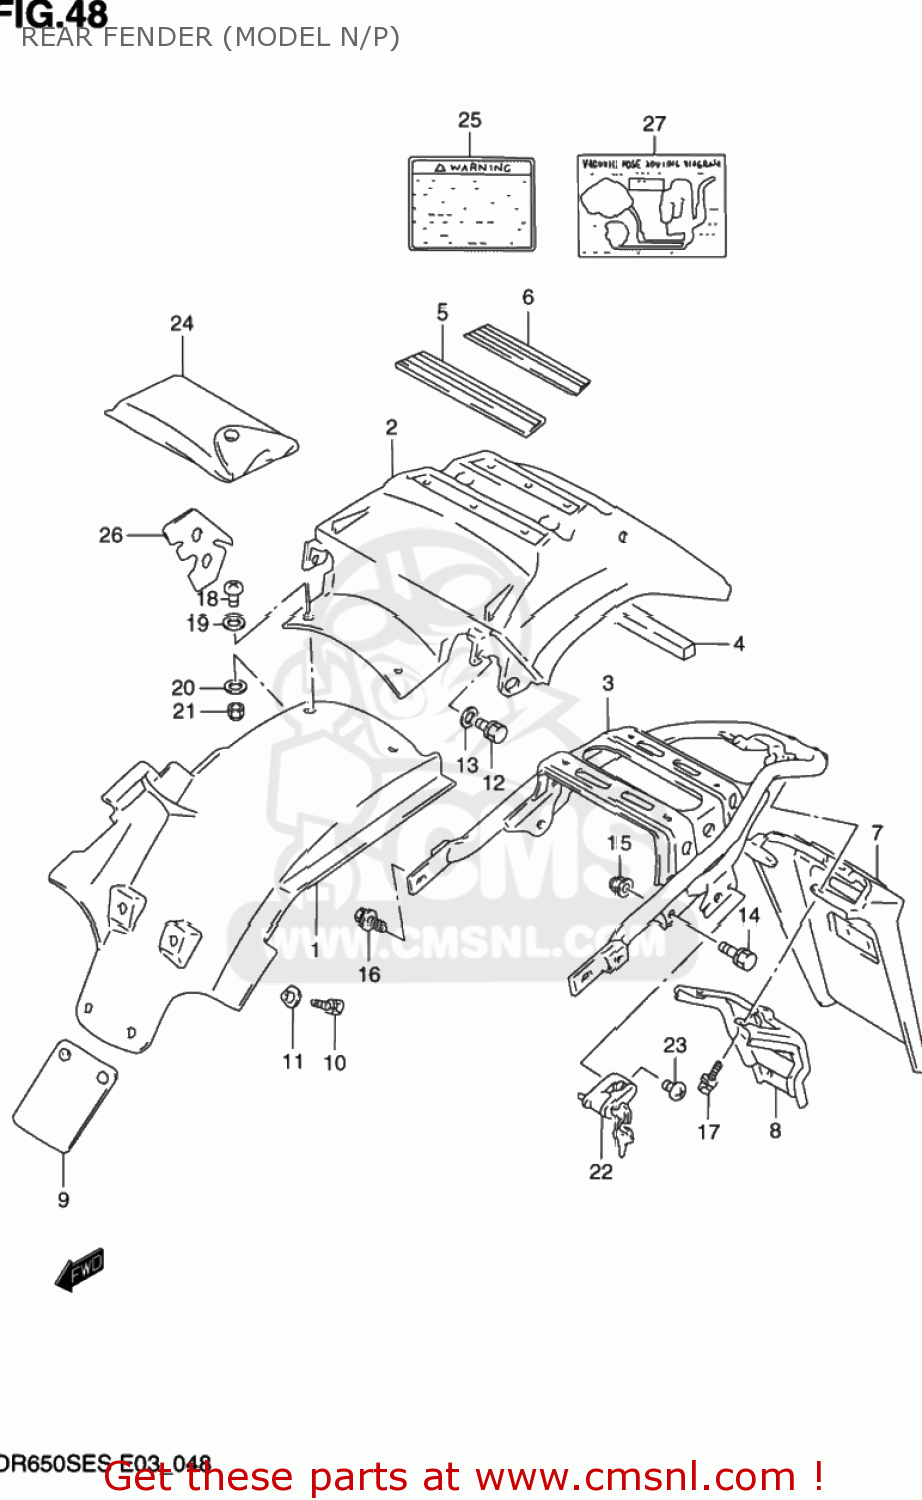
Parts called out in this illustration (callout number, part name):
1	BODY,REAR FENDER,FRONT
2	BODY,RR FENDER RR
3	REINFORCEMENT,REAR FENDER
4	CUSHION,REAR FENDER &
5	CUSHION,REAR FENDER,REAR
6	CUSHION,REAR FENDER,REAR
7	EXTENSION,RR FENDER
8	REINFORCEMENT,RR FENDER EXT
9	GUARD,RR FENDER FR MUD
10	BOLT
11	WASHER
12	BOLT
13	WASHER
14	BOLT,REINF,RH
15	NUT
16	BOLT(8X16)
17	BOLT(6X20)
18	SCREW
19	WASHER (5.5X16X1.2)
20	WASHER (5.5X16X1.2)
21	NUT
22	LOCK SET,HELMET
23	SCREW
24	TOOL ASSY
25	LABEL
26	SHIELD,REAR FENDER,REAR
27	LABEL (PIPING DIAGRAM)
28	LABEL,TIRE AIR PRESSURE
